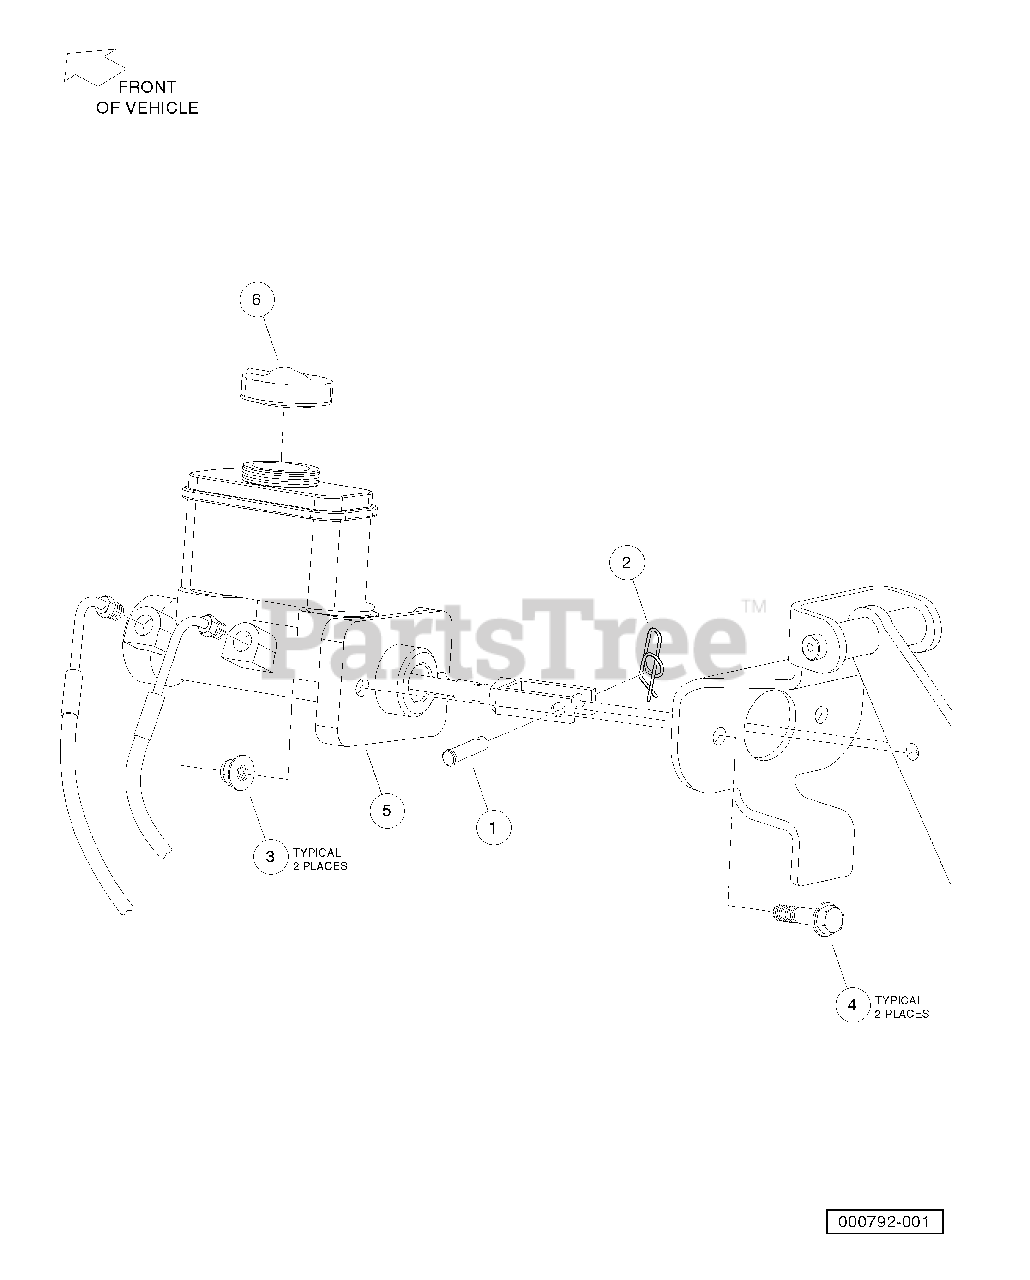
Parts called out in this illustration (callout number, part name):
1	Clevis Pin, 5/16 X 1
3	Nut,m8,all Metal Lock
4	Bolt Flanged Head, M8 X 1.25 X 35
5	Cylinder, Master, Integral Res
6	Filler Cap Asm Integral Res
